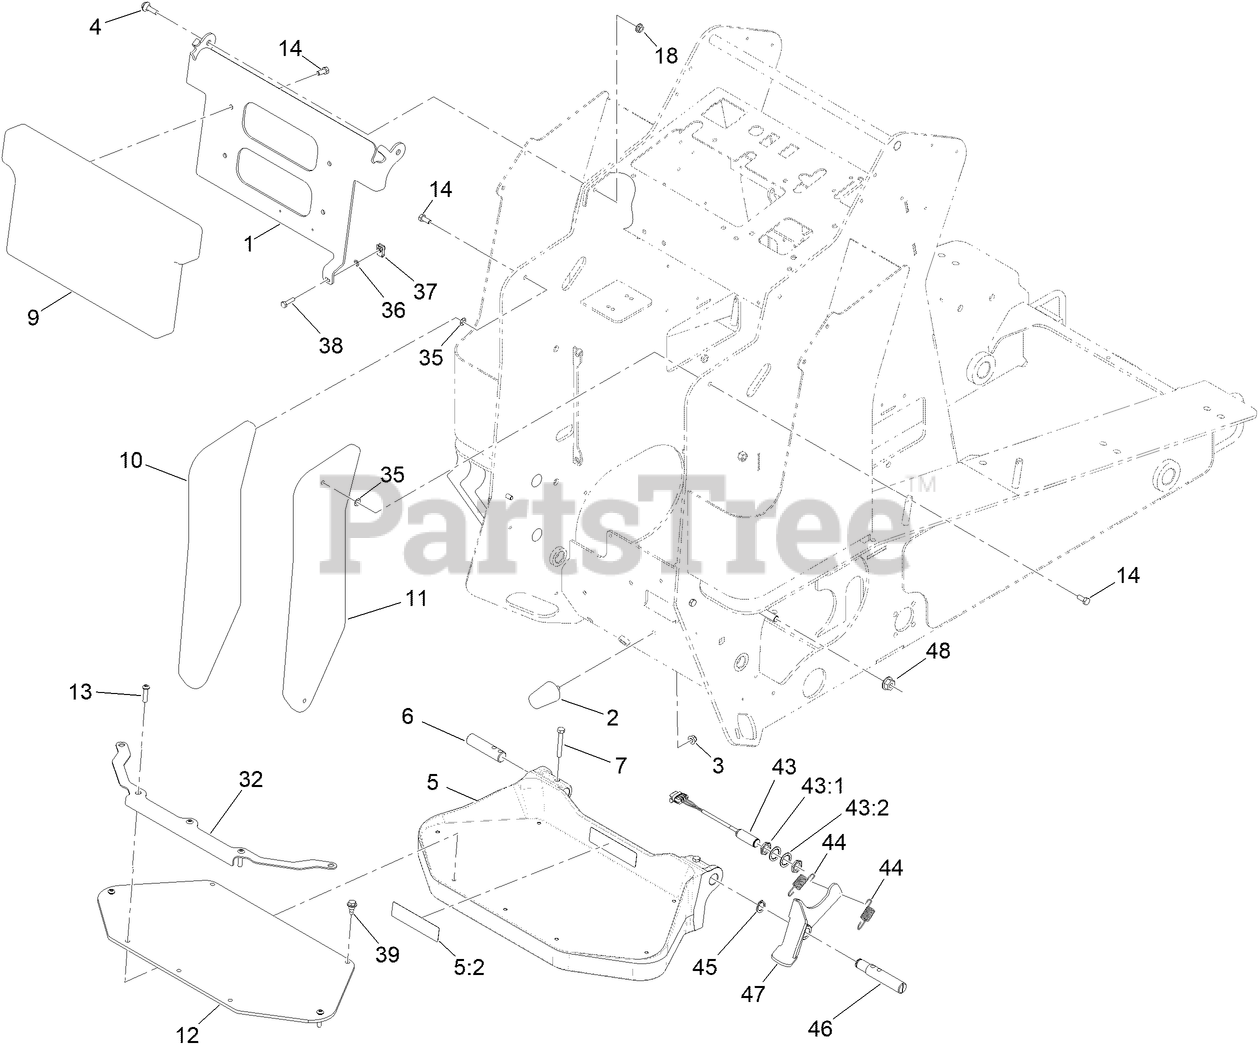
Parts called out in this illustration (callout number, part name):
1	HINGE-PAD
2	BUMPER
3	NUT-HF, NI
4	SCREW-SHOULDER
5	PLATFORM
5:2	DECAL-PARKING BRAKE
6	PIN-PIVOT
7	SCREW-HH
9	CUSHION-PAD
10	CUSHION-PAD
11	CUSHION-PAD
12	PAD-FOOT
13	SCREW-HSBH
14	SCREW-HH
18	NUT-HF
32	PLATE - CLAMP
35	NUT-PUSH
36	NUT-RETAINING
38	SCREW-HH
39	BOLT-SHOULDER
43	PROXIMITY SWITCH ASM
43:1	NUT-HEX
43:2	WASHER-LOCK, INTERNAL TOOTH
44	SPRING-EXTENSION
45	RING-RETAINING
46	PIN-PLATFORM
47	PEDAL ASM
48	NUT-HHF
